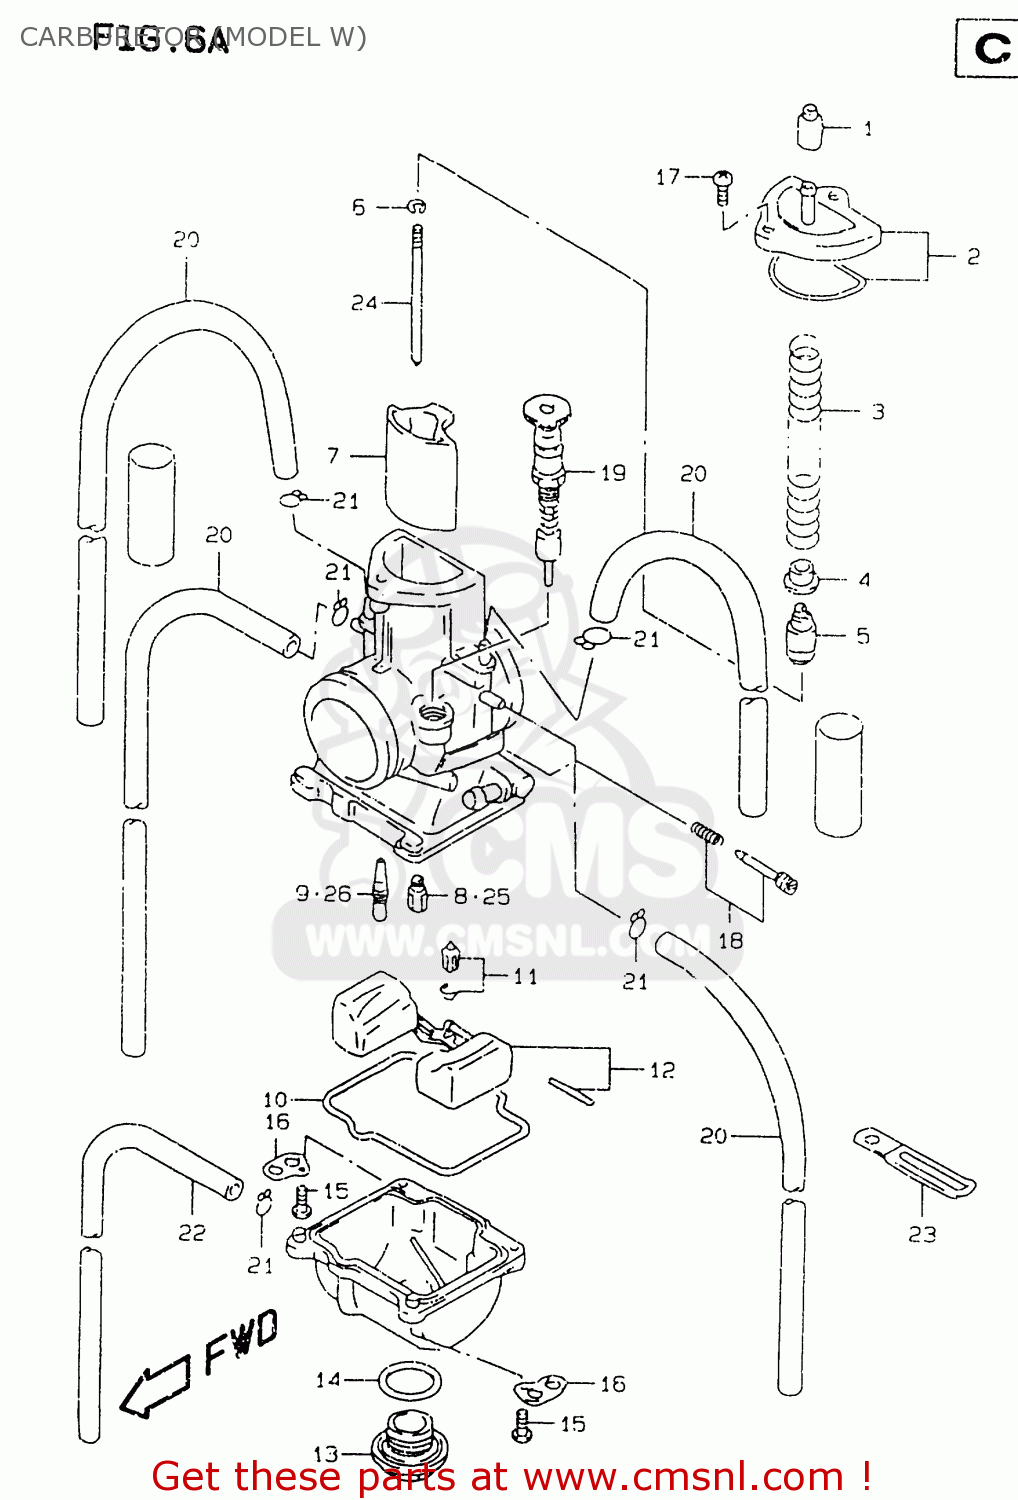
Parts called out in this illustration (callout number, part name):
1	CAP,CARBURETOR
2	CAP SET,TOP
3	SPRING,THROTTLE VALVE
4	COLLAR,THROTTLE VALVE
5	HOLDER,CABLE
6	CLIP,NEEDLE
7	VALVE,THROTTLE
8	JET,MAIN(175)
9	JET,SLOW(55)
10	GASKET,FLOAT CHAMBER
11	VALVE SET,FLOAT
12	FLOAT SET
13	BOLT,DRAIN
14	O RING
15	SCREW
16	PLATE
17	SCREW
18	SCREW SET,AIR
19	STARTER VALVE
20	HOSE(4X7X620)
21	CLIP
22	HOSE(3.5X6.5X600)
23	CLAMP(L:45)
24	NEEDLE(R1469MS)
25	JET,MAIN(145)
26	JET,SLOW(35)
